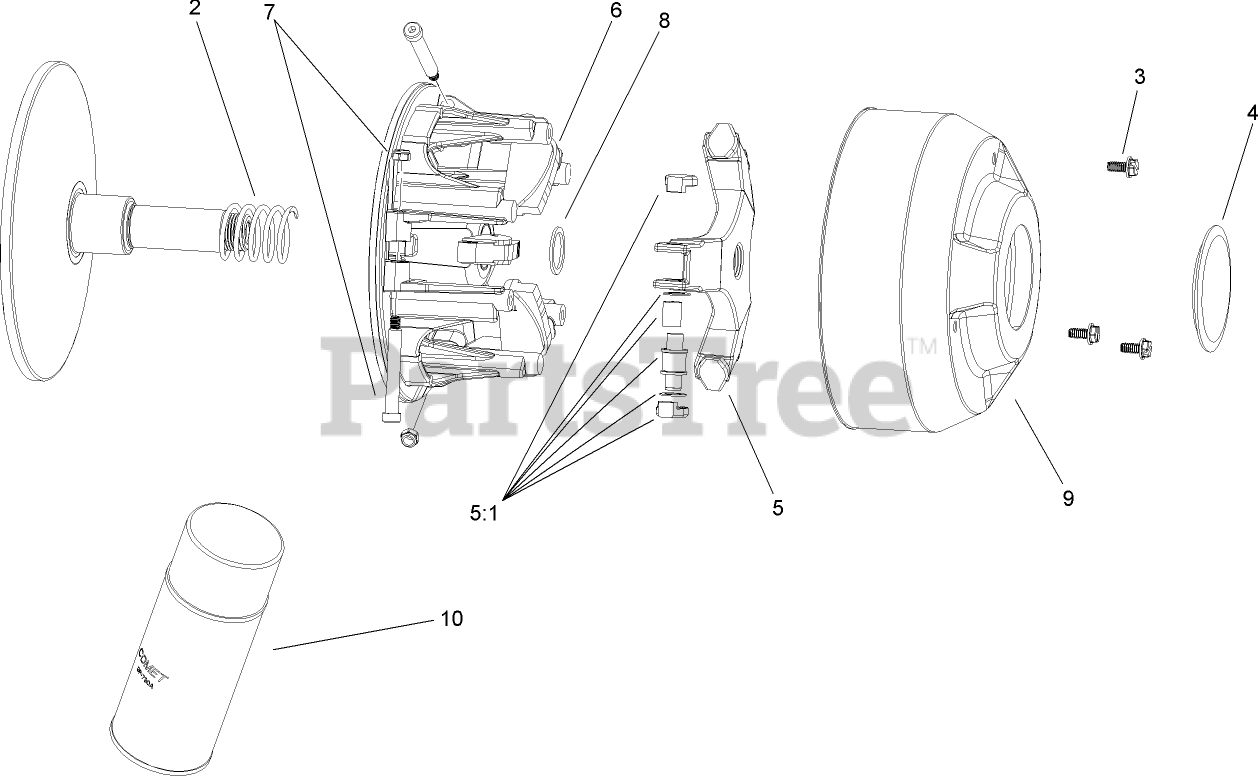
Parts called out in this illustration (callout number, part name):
2	SPRING
3	SCREW-HHF
5	SPIDER ASM
5:1	SPIDER REPLACEMENT PARTS KIT
6	ARM-CAM
7	PIVOT BOLT AND NUT KIT
